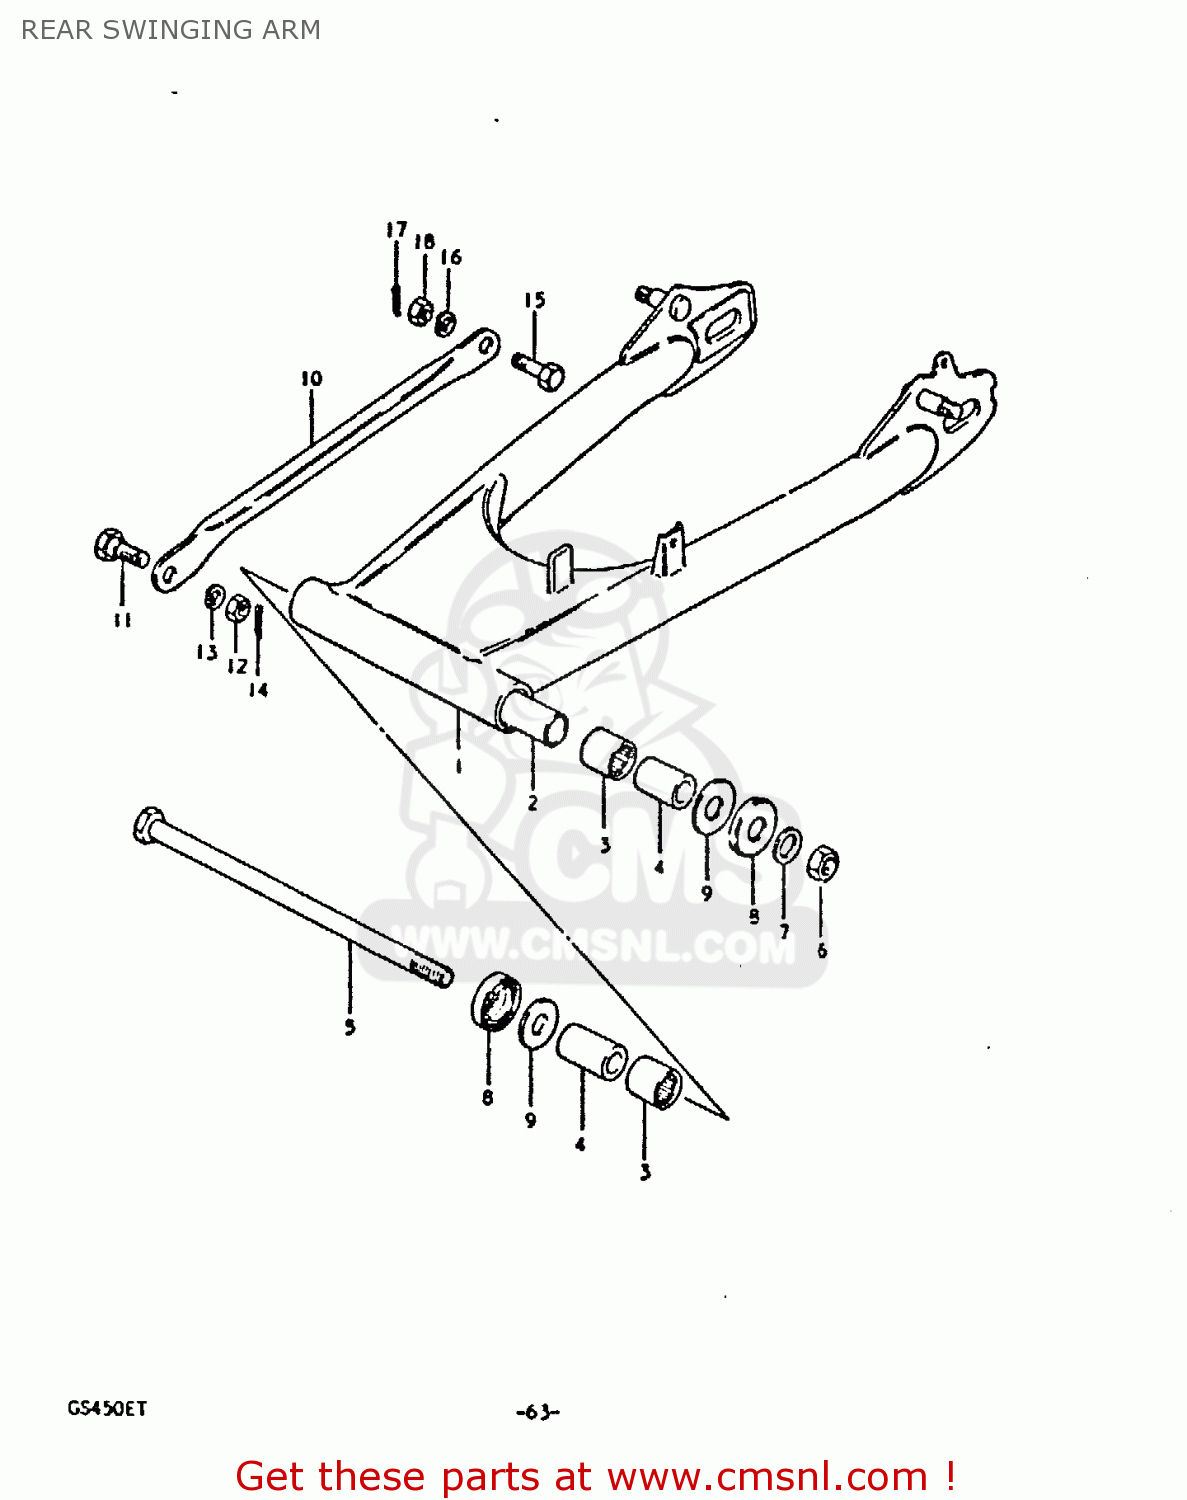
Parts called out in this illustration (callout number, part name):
1	SWING ARM ASSEMBLY,REAR
2	SPACER,SWINGINGARM CTR
3	BEARING(22X29X30)
4	SPACER,RR SWGARM PIVOT
5	SHAFT,REAR SWING ARM
6	NUT 14MM
7	WASHER
8	CVR,RR SWGARM DUST SEAL(OD:40)
9	WASHER(14.2X34X1)
10	TORQUE LINK,REAR
11	BOLT(10X24.5)
12	NUT
13	LOCK WASHER
14	PIN
15	BOLT(10X31)
16	LOCK WASHER
17	PIN
18	NUT
